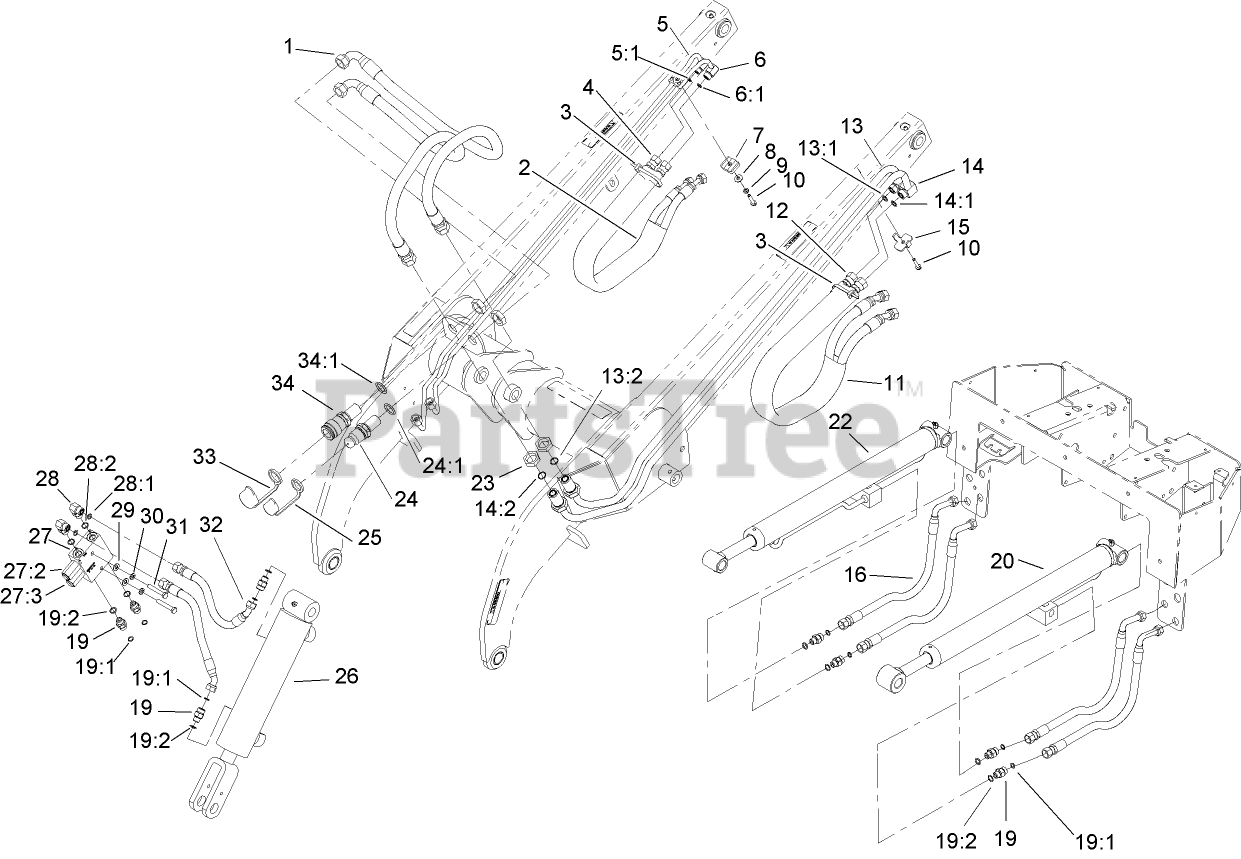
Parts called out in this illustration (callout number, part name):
1	HOSE ASM
2	SLEEVE-PROTECTIVE
3	TIE-CABLE
4	HOSE-HYD
5	HYD TUBE ASM
5:1	O-RING
6	HYD TUBE ASM
6:1	O-RING
7	CLAMP-TUBE
8	WASHER-FLAT
9	WASHER-LOCK
10	SCREW-HWH
11	SLEEVE-PROTECTIVE
12	HOSE-HYD
13	HYD TUBE ASM
13:1	O-RING
13:2	O-RING
14	HYD TUBE ASM
14:1	O-RING
14:2	O-RING
15	PLATE-CLAMP, TUBE
16	HOSE-HYD
19	FITTING-STRAIGHT
19:1	O-RING
19:2	O-RING
20	LH LIFT CYLINDER ASM
22	RH LIFT CYLINDER ASM
23	NUT-LOCK, BULKHEAD
24	BULKHEAD NIPPLE ASM
24:1	O-RING
25	CAP-DUST, NIPPLE
26	TILT CYLINDER ASM
27	VALVE-RELIEF, CROSSOVER
27:2	CARTRIDGE-RELIEF
27:3	CARTRIDGE-RELIEF
28	FITTING-ELBOW, 90 DEG
28:1	O-RING
28:2	O-RING
29	WASHER-PLAIN
30	WASHER-LOCK
31	SCREW-HH
32	HOSE-HYD
33	CAP-DUST, COUPLER
34	BULKHEAD COUPLER ASM
34:1	O-RING
